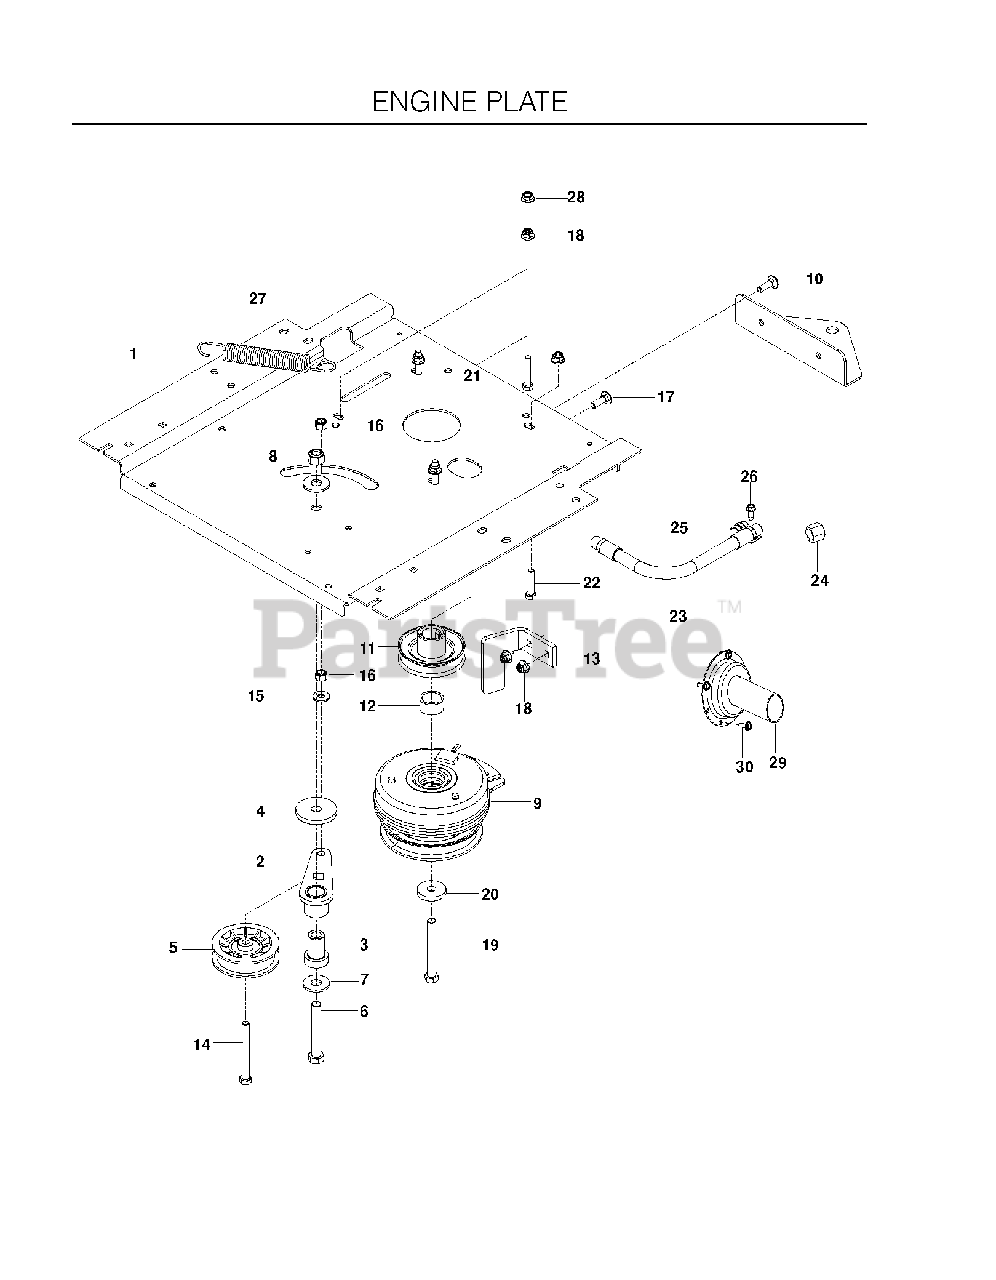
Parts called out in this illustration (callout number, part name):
1	PLATE, ENGINE BLK
2	IDLER ARM WELDMENT
3	IDLER SPINDLE
4	HEAVY WASHER
5	PULLEY, IDLER
6	HCS 1/2C X 3 1/4
7	WASH USS FLAT 1/2
8	NUT 1/2-13 HEX NYLOC ZD
9	CLUTCH, 105 FT-LBS
10	HITCH, BLACK
11	PULLEY, ENGINE
12	T & B SPACER
13	STOP, CLUTCH, BLACK
14	HCS 3/8-16X3 1/2 GR5
15	WASHER 5/16 FLAT
16	NUT 3/8-16 NYLOC
17	RHSNB 5/16C X 1
18	5/16-18 NYLOC FLANGE NUT
19	HCS 7/16-20X3-1/2 GR 5 ZN
20	CLUTCH, WASHER
21	HCS 5/16C X 1 3/4
22	CAPSCREW 5/16 X 1/1/2 HEX HEAD
23	OIL DRAIN HOSE
24	DRAIN CAP
26	SCREW 1/4 X 5/8
27	SPRING, DECK DRIVE
28	NUT 5/16C WHIZ
29	MUFFLER EXTENSION
30	SCREW, TAP #10-16 X 1/2
